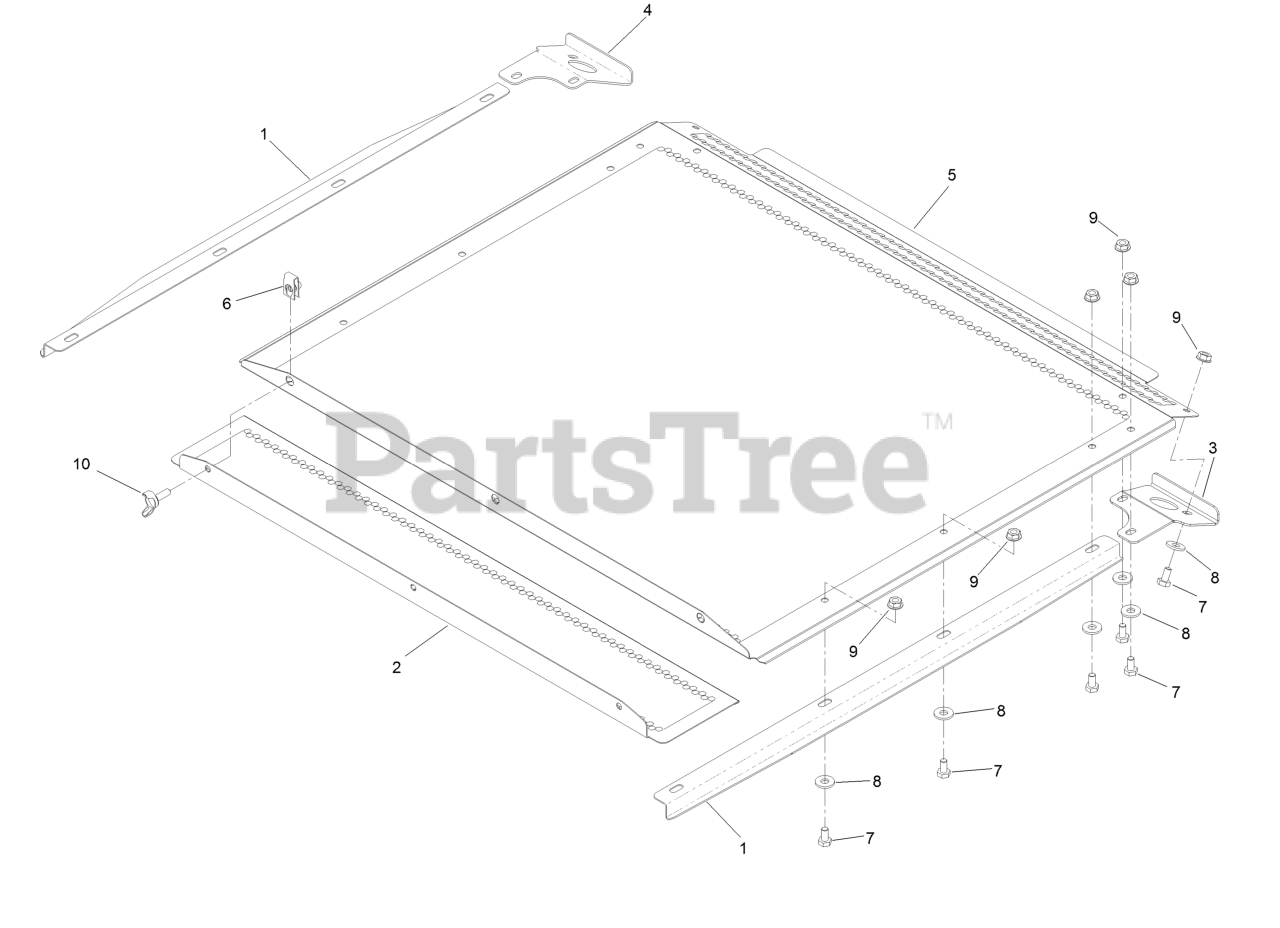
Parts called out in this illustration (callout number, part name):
1	Guide-Screen
2	Panel-Screen, Removable
3	Handle-Screen, LH
4	Handle-Screen, RH
5	Panel-Screen, Hopper
7	Screw-HH
8	Washer-Flat
10	Screw-Wing
